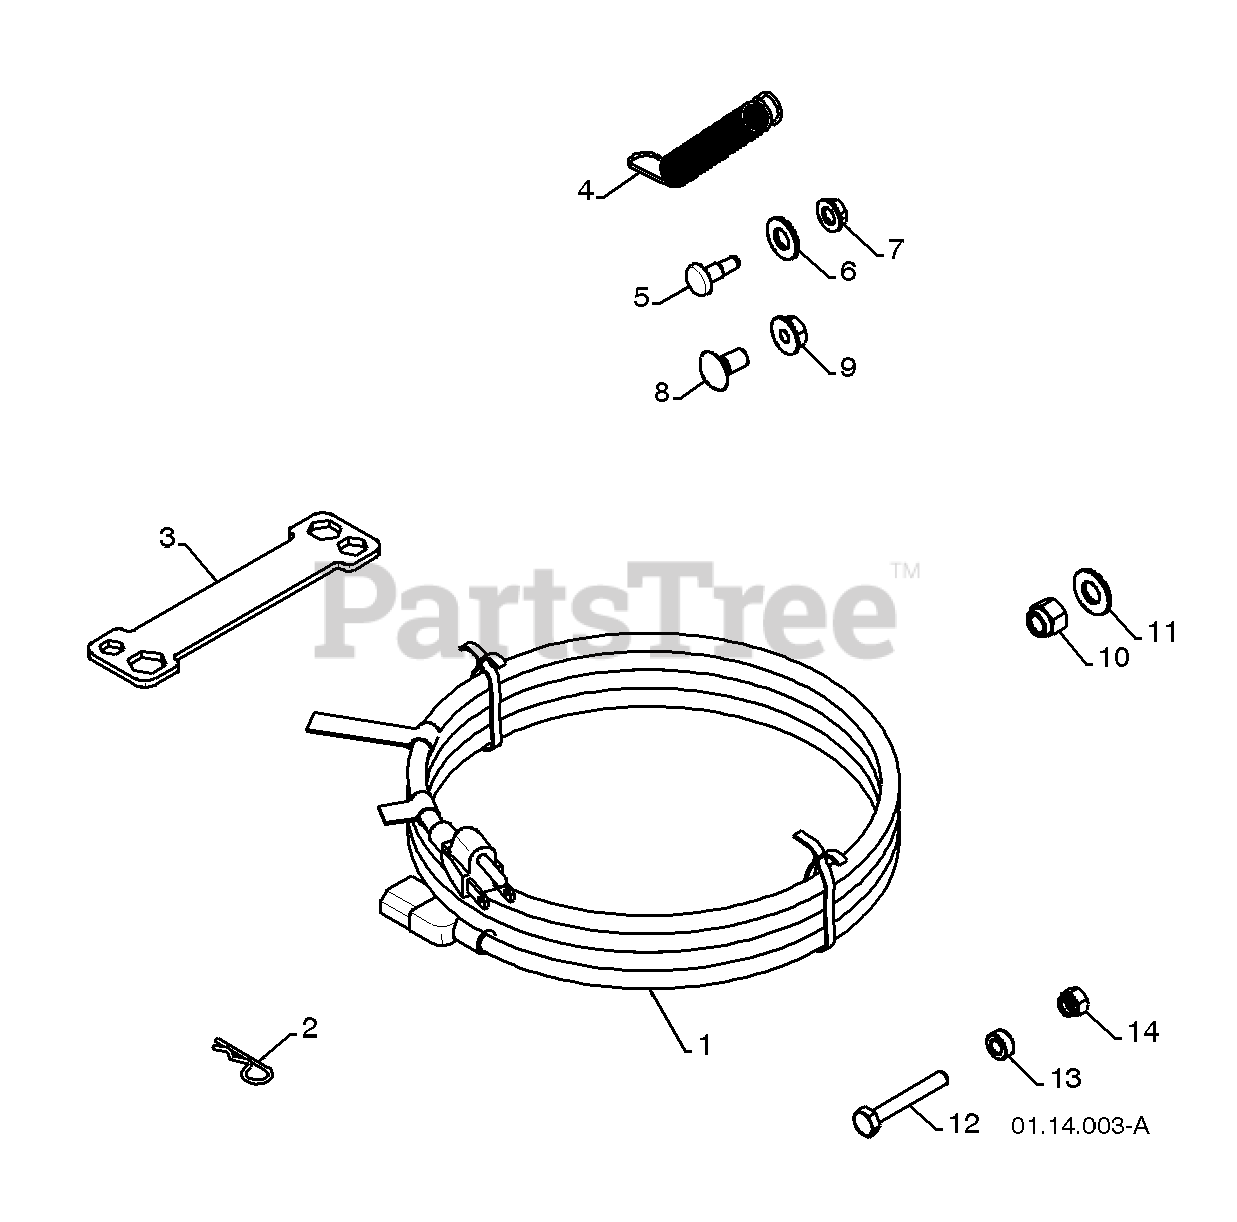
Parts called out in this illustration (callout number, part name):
1	POWER CORD
2	RETAINER PIN
3	WRENCH
4	REMOTE SPRING
5	SHOULDER BOLT 1/4-20
6	NYLON WASHER 1/4-20
7	LOCKNUT 1/4-20
8	CARRIAGE BOLT 5/16-18 X 5/8
9	LOCKNUT 5/16-18
10	LOCKNUT 3/8-16
11	WASHER 3/8
12	SHEAR BOLT 1/4-20 X 1-3/4
14	LOCKNUT 1/4-20
